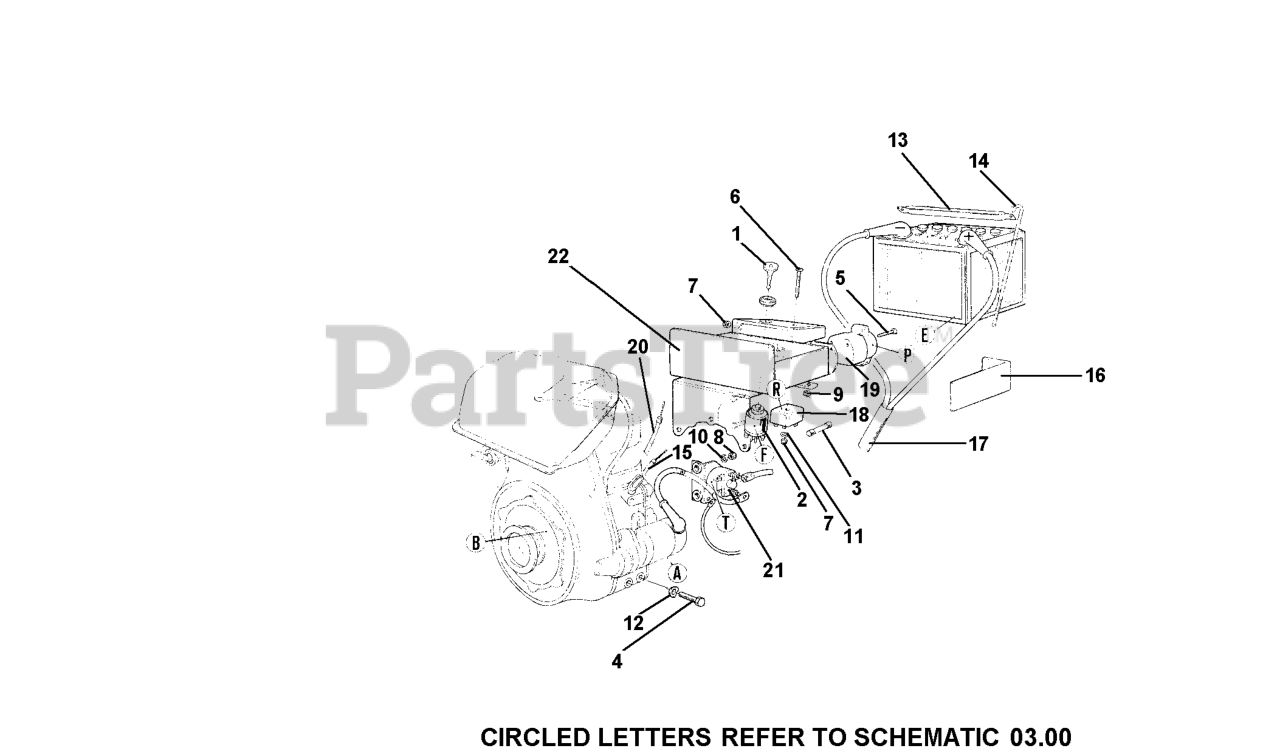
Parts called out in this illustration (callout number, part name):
3	FUSE 6 X 25 25A
4	SCREW TE M8 X 12
5	SCREW TCCEI M4 X 30
6	SCREW TC M4 X 30 UNI 6107
9	NUT, SELF LOCKING M6
10	WASHER, FLAT 6.4
11	LOCK WASHER B 4.3
12	WASHER, LOCK 8.4
13	BATTERY BRACKET
14	BATTERY TIEROD
15	CABLE & SHEATH ACCEL.LOMBAR
16	ANTISHOCK BAT
17	ELECTRIC START CABLES MC 715
19	7-POLE SOCKET
20	SHEATH CABLE
21	BOSCH RELAY 0332002160
22	SUPPORT BATTERY
